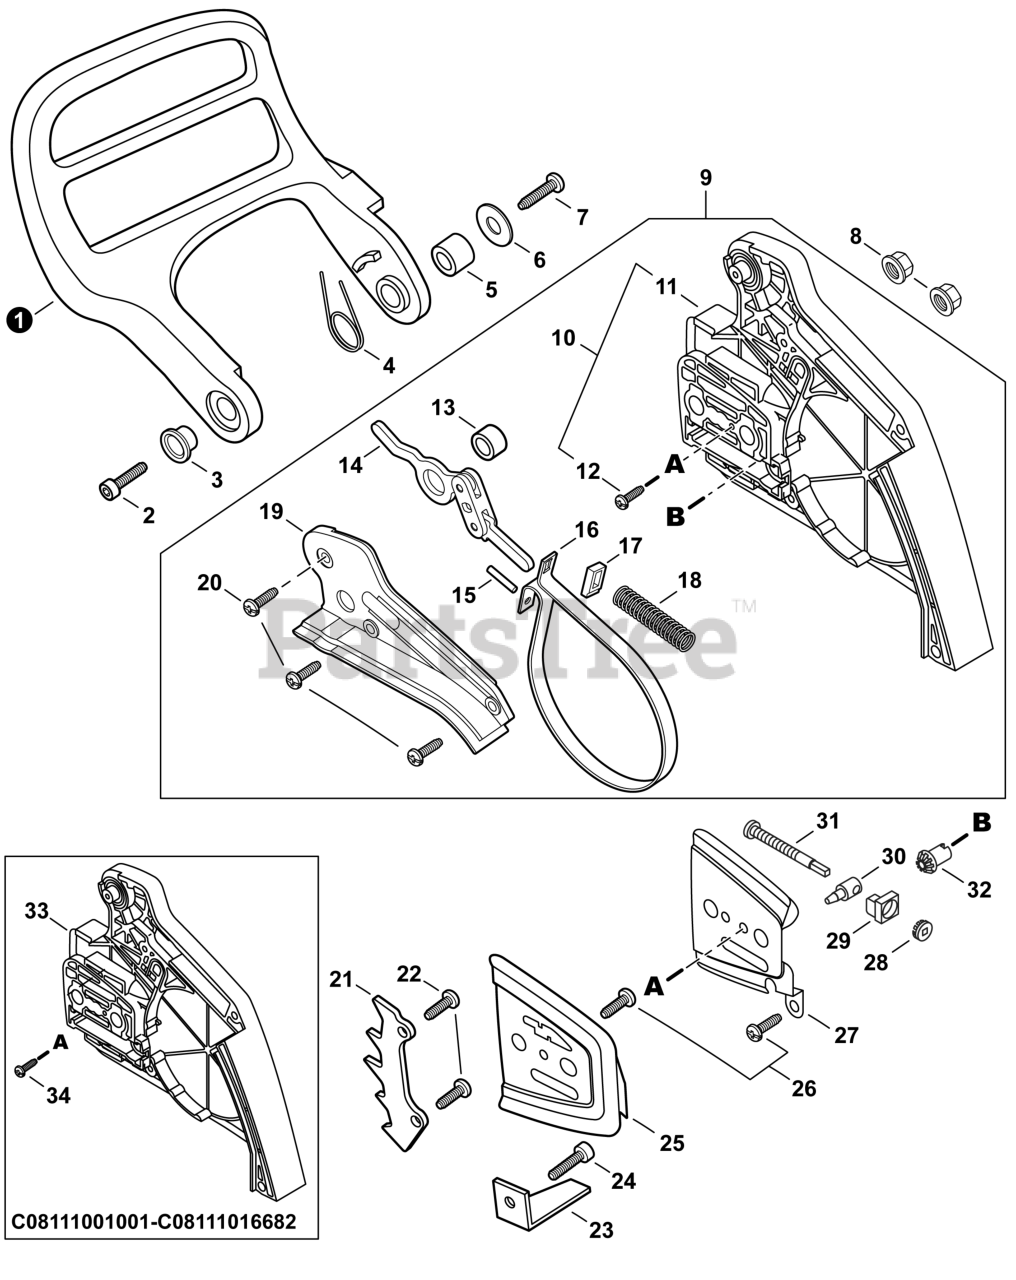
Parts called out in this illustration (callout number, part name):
1	LEVER, BRAKE
2	SCREW TAPPING 5×16
3	COLLAR 10
4	SPRING, TORSION
5	SPACER 8×12×9
6	WASHER 4.2×16.5×1
8	NUT, FLANGE M8×1.25
9	BRAKE ASSY, CHAIN
10	SPROCKET GUARD SET
11	GUARD, SPROCKET
12	SCREW 3×5
13	SPACER 8×12×9
14	CONNECTOR, BRAKE
15	PIN, SPRING 3×9.8
16	BAND, BRAKE
18	SPRING, COMPRESSION
19	COVER, BRAKE
20	SCREW 4×12
21	SPIKE, BUMPER
22	SCREW TAPPING 5×20
23	CHAIN CATCHER
24	SCREW TAPPING 5×16
25	PLATE, GUIDE - INNER
26	SCREW 4×12
27	PLATE, GUIDE - OUTER
28	GEAR, BEVEL
29	COLLAR 8
30	TENSIONER, CHAIN
31	SCREW, CHAIN TENSION
32	GEAR, BEVEL
33	SPROCKET GUARD SET
34	SCREW 3×6
